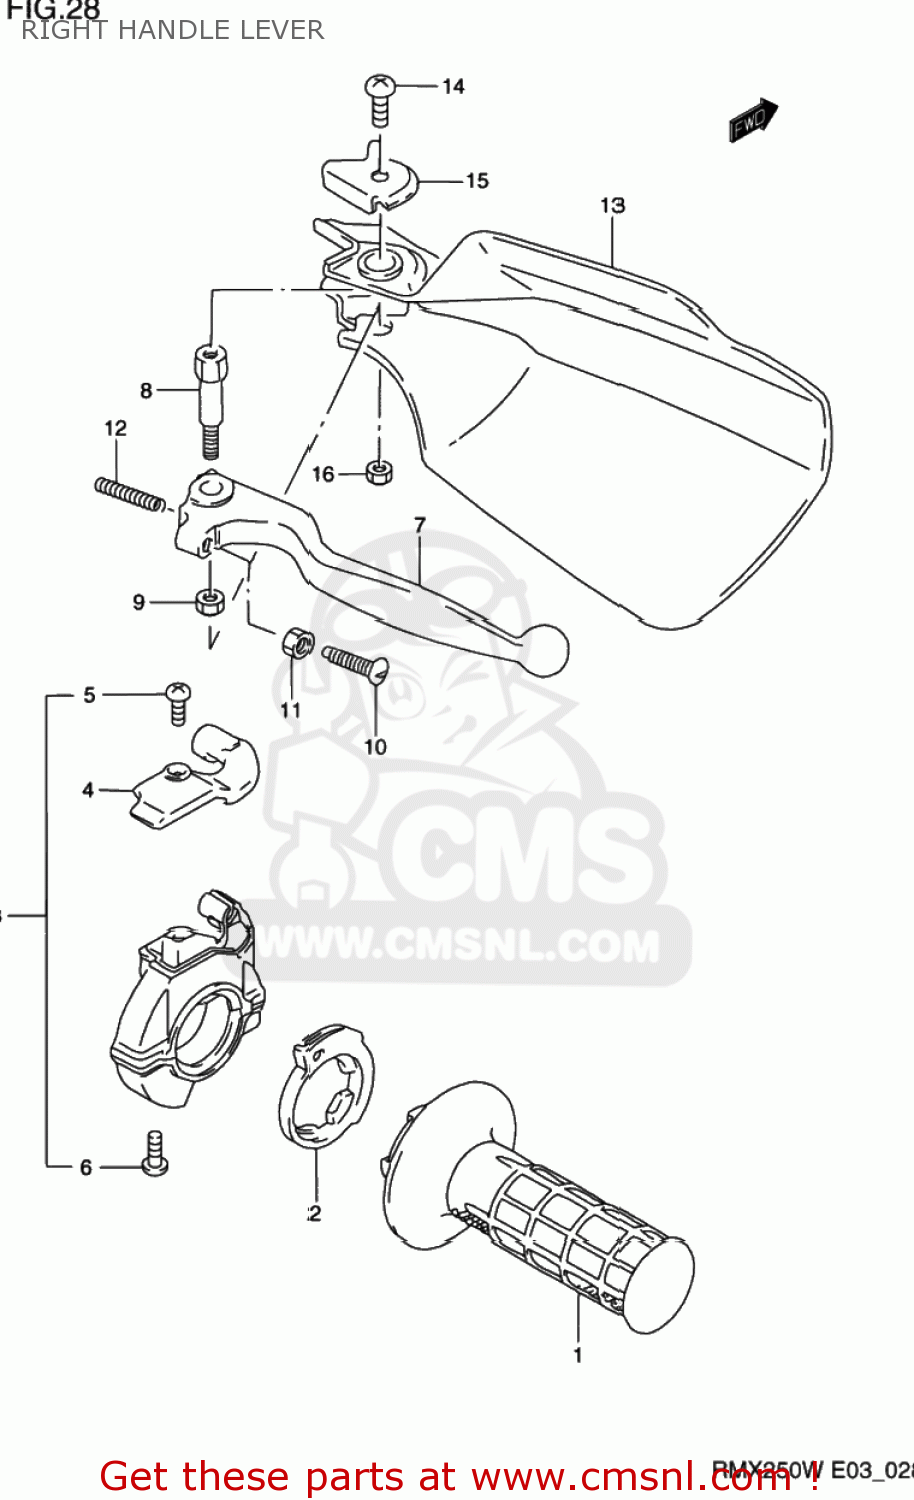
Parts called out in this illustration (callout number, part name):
1	GRIP,THROTTLE
2	ROTOR,THROTTLE GRIP
3	CASE ASSY,THROTTLE
4	COVER,THROTTLE CASE
5	SCREW,UPPER
6	SCREW
7	LEVER,BRAKE
8	BOLT,BRAKE LEVER PIVOT
9	NUT 6MM
10	BOLT,ADJUST
11	NUT
12	SPRING,RETURN
13	COVER,KNUCKLE,RIGHT
14	SCREW
15	PLATE,KNUCKLE COVER,R UPR
16	NUT 6MM
